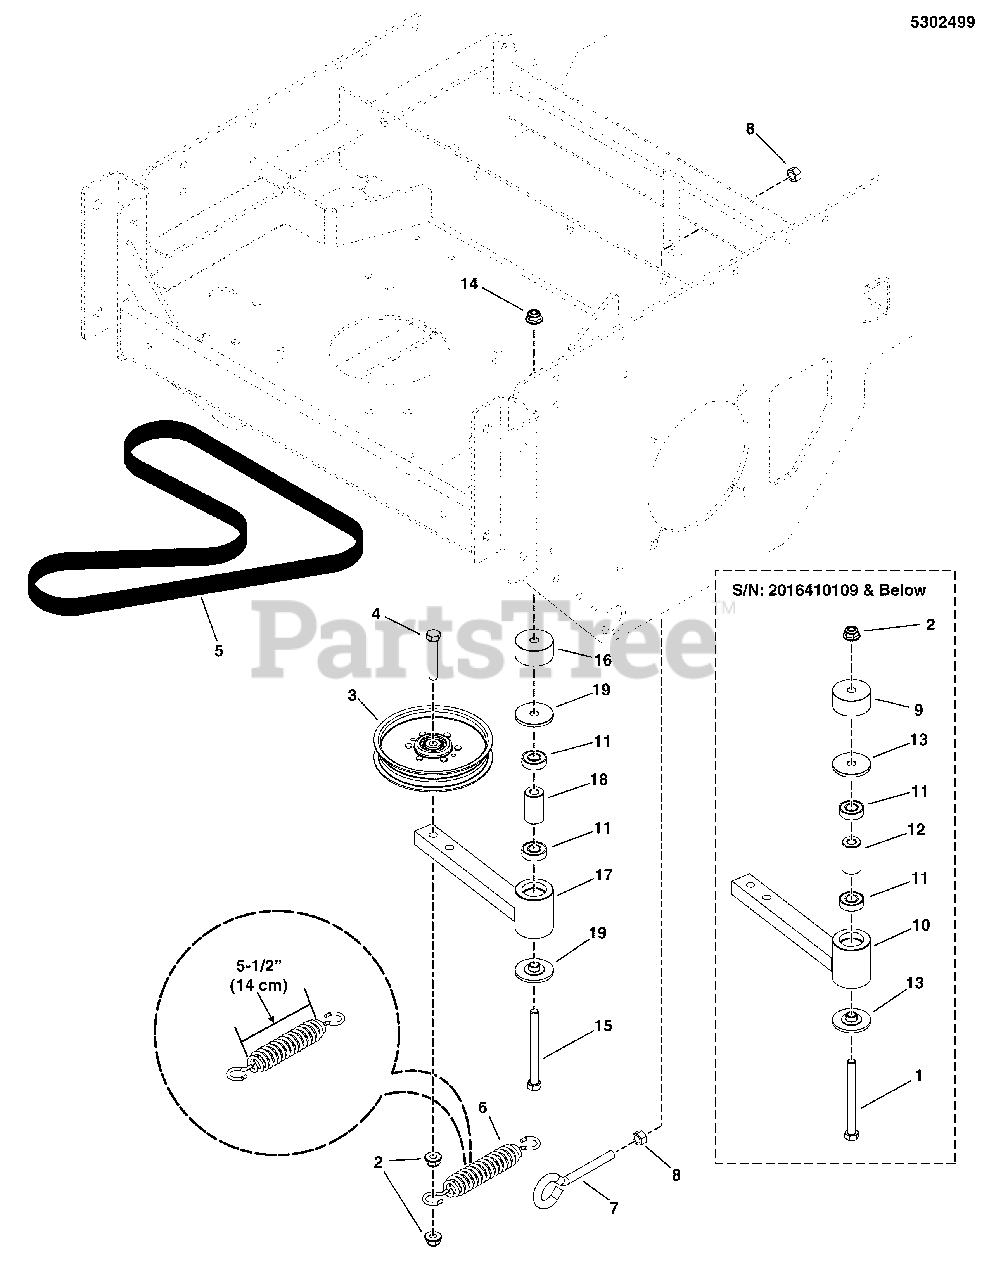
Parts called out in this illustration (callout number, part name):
1	BOLT, 3/8-16 X 4" GD5 CZ
2	NUT, 3/8-16 HEX NYLOCK FLANGE
3	PULLEY, IDLER, SINGLE FLANGE
4	BOLT, 3/8-16 X 2-3/4" GD5 CZ
5	BELT, HB, 65.1"EL
6	SPRING-EXT, 1.04 ODX6.935LGX.148WR, BLK
7	EYE BOLT, 3/8-16 X 5, 2.88THRD, 1EYE, CZ
8	NUT, 3/8-16 HEX
9	SPACER, .39 X 1.75 X .63, CZ
10	ASSM, IDLER ARM, PUMP DRIVE, 3/8ID, CAST
11	BEARING, BALL, AXLE
12	SPACER, .39 X .88 X 1.53, CZ
13	SPACER, IDLER ARM, T-STYLE, CZ
14	NUT, Hex Flange, Nylock, 1/2-13
15	BOLT, 1/2-13 X 4" GD5 CZ
16	SPACER, .52 X 1.75 X .63, CZ
17	ASSM, IDLER ARM, PUMP DRIVE, 1/2ID, CAST
18	SPACER, .52 X .84 X 1.53, CZ
19	SPACER, IDLER ARM, 1/2, PM
